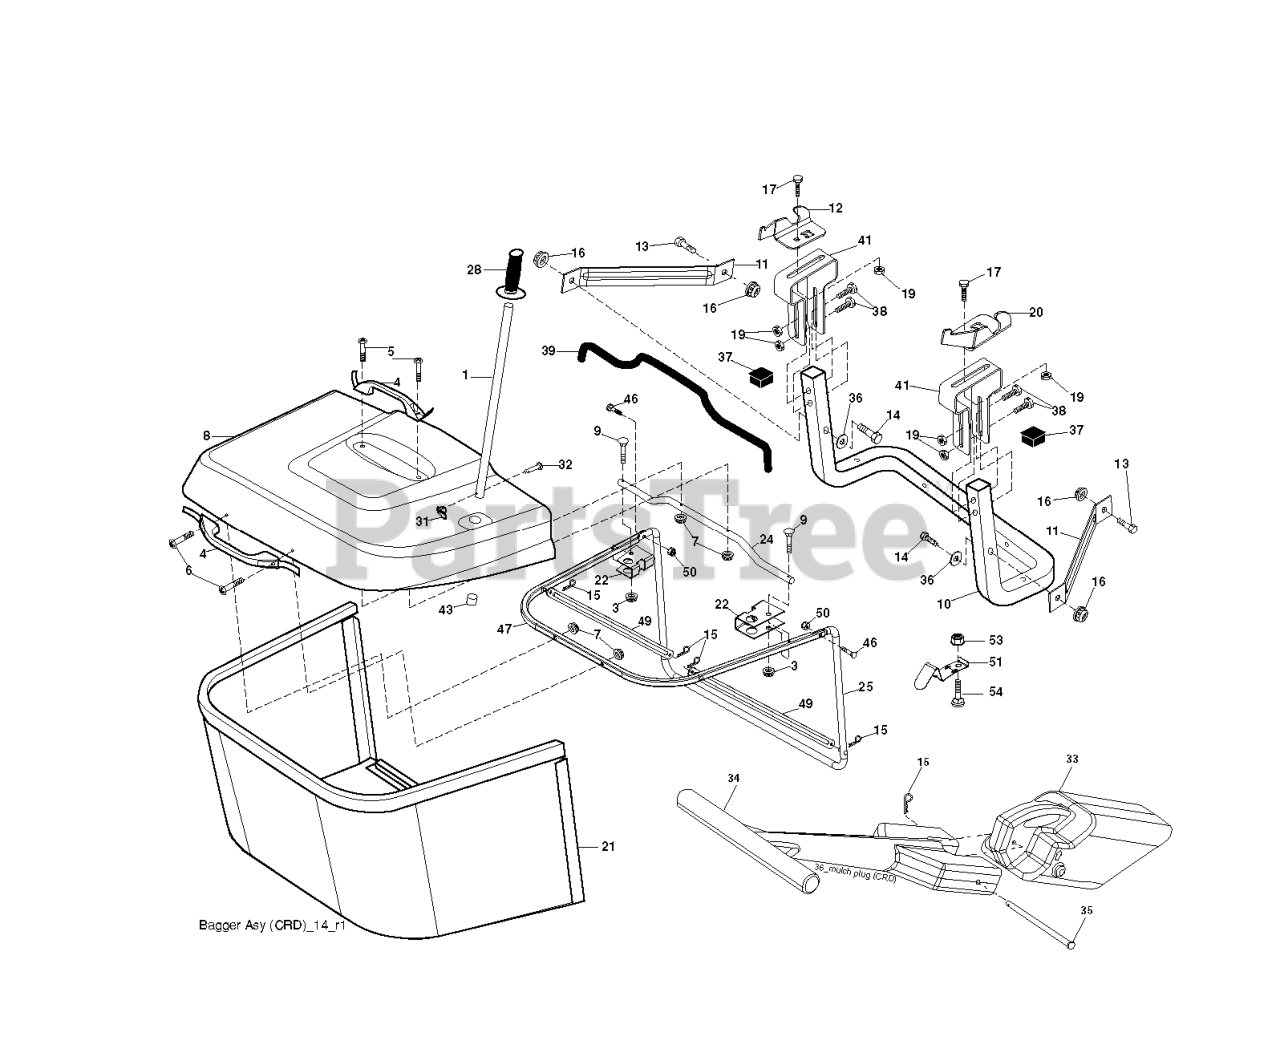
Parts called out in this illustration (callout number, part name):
1	TUBE HANDLE
3	NUT T
4	HANDLE.BAGGER.W/LVRS.BLK.CRD
5	SCREW.PAN.HEAD
6	REPL BY 532 75 00-29
8	COVER.PNT.BGR.CRD.WSLOTS.MS668
9	Bolt Carriage 1/4-20 x 2.25d x Gr.5
10	TUBE
11	BRACKET.SUPPORT.UPPER.BAG.CRD
12	BRKT PIVOT
14	BOLT-HEX EAK
15	RETAINER-SPRNG RB
16	NUT LOCK FLG 3/8-16 UNC
17	RP BOLT 5/16-18 X3/4 ZN/YEL GR
19	NUT LOCK HEX FLANGE 5/16-18
20	BRKT.PIVOT.RH.CRD
21	BAGGER.ASM.CRD.2007
22	BRKT.SIDE.BAG.CRD
24	TUBE.PIVOT.BAG.CRD.BLACK
25	PIPE
28	GRIP.HANDLE.BLACK
31	RETAINER CLIP
32	RIVET,DRILLED
33	MULCH PLUG, CTH150
34	HANDLE.MULCHER.92.CRD (2 2)
36	WASHER
37	Plug Support Bagger CRD
38	BOLT.5/16-18X2.5
39	SEAL.BAGGER.CRD
41	BRKT.VERT.ADJ.BAGGER.CRD
43	PLUG, TUBING END
46	BOLT.CARRIAGE.5/16-18
47	PIPE
49	ROD
50	NUT.71038.31-18.HEX.NYLOCK
51	LATCH
53	NUT
54	BOLT
